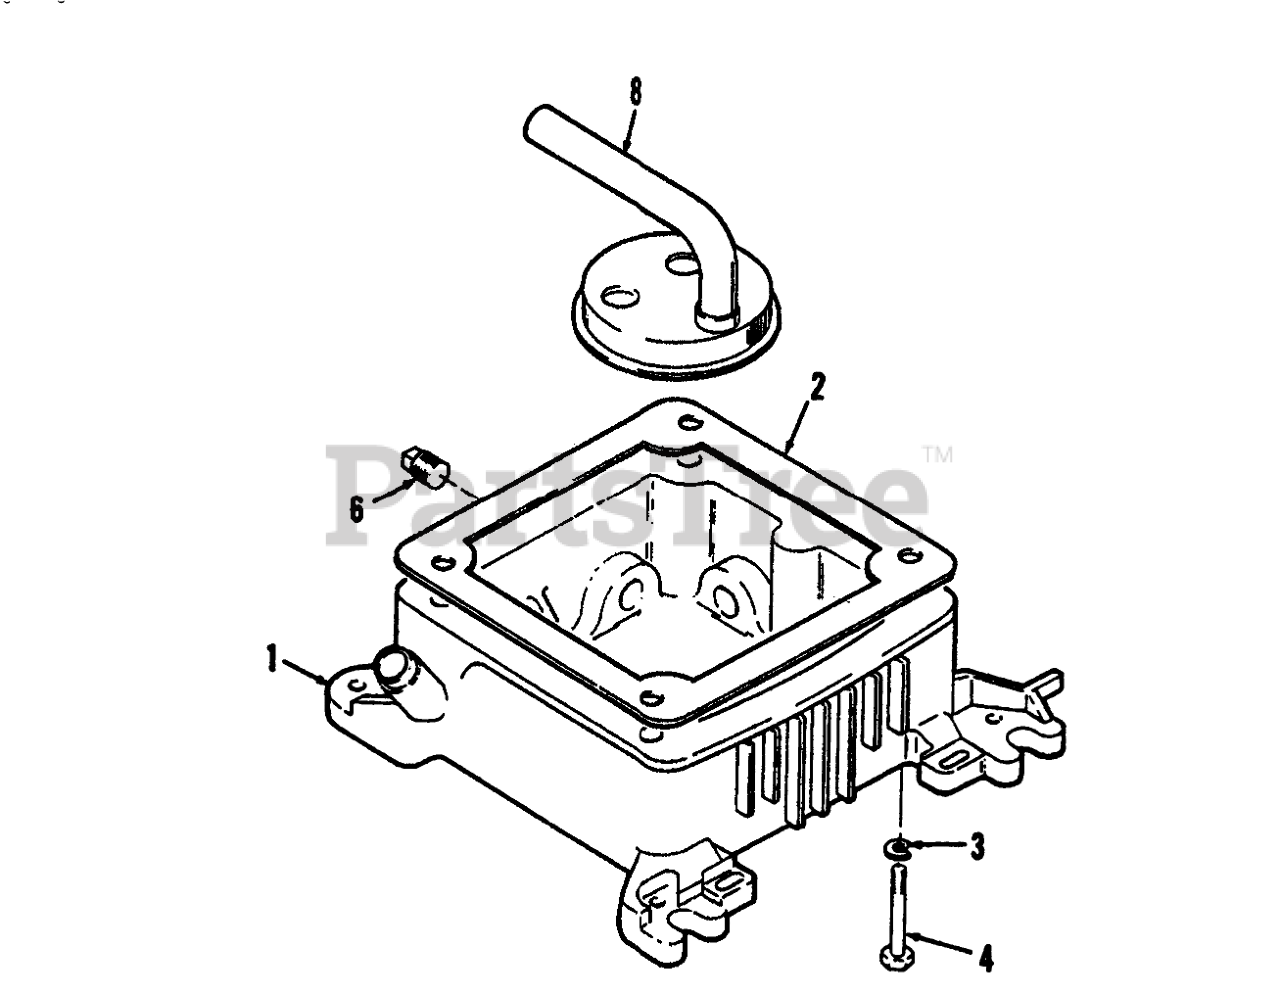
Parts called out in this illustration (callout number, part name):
1	Base-Oil (Includes All Plugs & Plug Gasket)
2	GASKET
3	WASHER-FLAT
4	HHCS 3/8-16 X 3 3/4
6	PLUG - SQUARE HEAD
8	Cup-Oil Pump Intake
